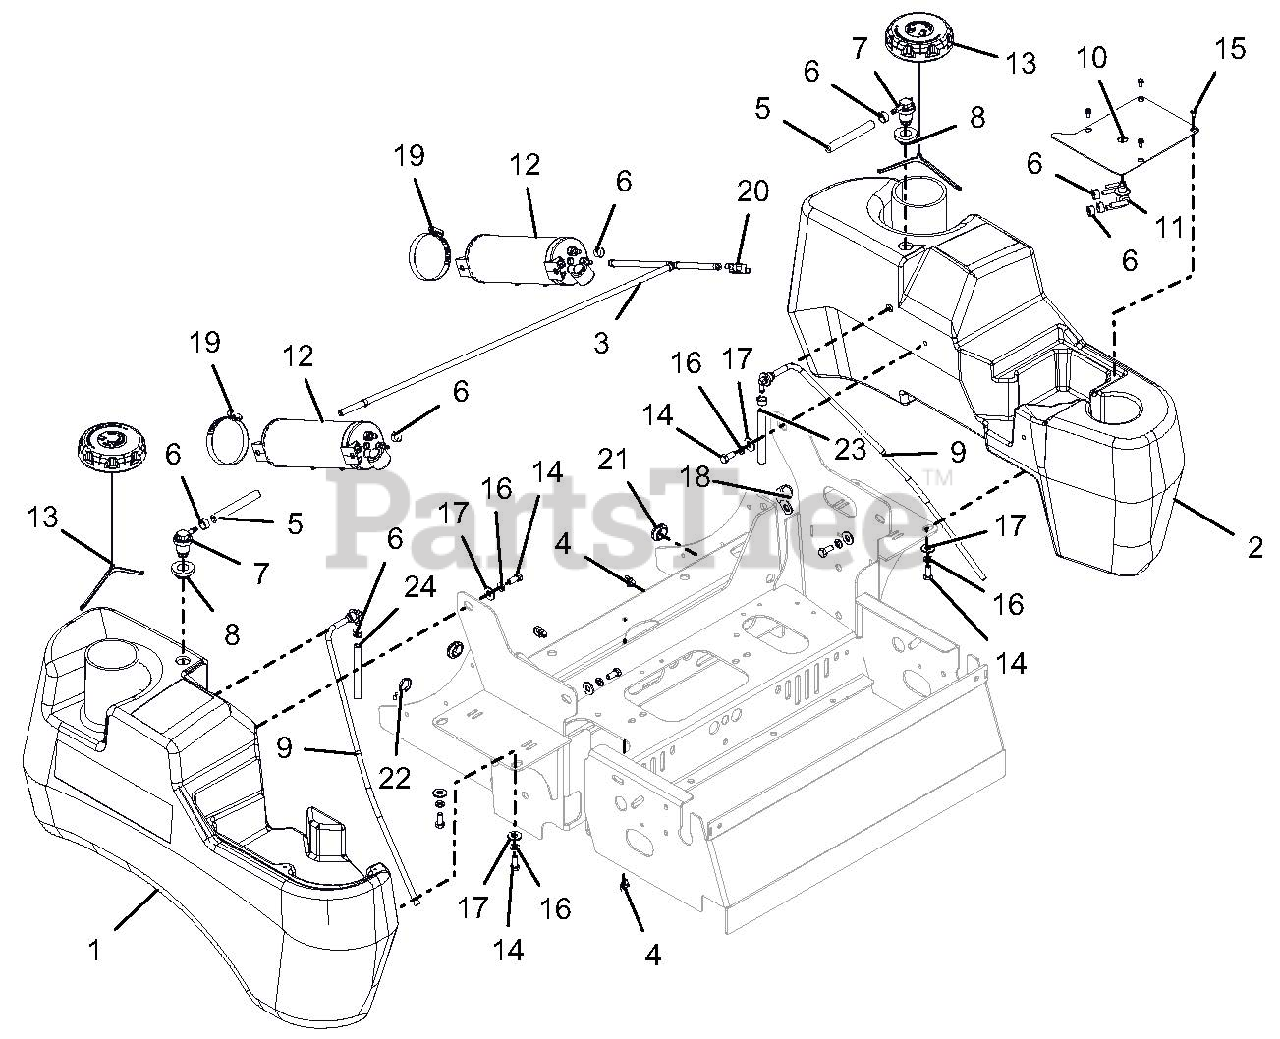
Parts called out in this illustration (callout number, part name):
1	TANK, RH LARGE GRAVELY FUEL
2	TANK, LH LARGE GRAVELY FUEL
3	PT200-400 KAW CARB FUEL LINE ASSEMBLY
4	CLIP, ROUTING
5	.25 LOW-PERM GAS HOSE 19.00" LG - LH TANK TO VALVE
6	CLAMP, FUEL LINE
7	VALVE, COMBINATION
8	GROMMET, REMOTE VENT NITRILE
9	ASM, LARGE TANK FUEL PICKUP
10	PLATE, FUEL VALVE MOUNTING-RED
11	VALVE, FUEL
12	CANISTER, CARBON 9.3 GAL
13	CAP, NON NONVENT AUTOLOCK
14	BLT-HEX .31-18X.75 GR5 YWZC
15	SCR-MCH 10-24X.38 HWHSTAINLESS
16	WSHR-LK .31X.078 REG YWZC
17	WSHR-FL-STL.38X.875X.083 YWZC
18	CLAMP, CUSHIONED STEEL .75
19	CLAMP, HOSE 2.3/3.2
20	CLIP, T, .38-.50
21	GROMMET, RUBBER
22	CABLE TIE W/ TREE
23	.25 LOW-PERM GAS HOSE 14.00" LG - Tank vent to CARB canister
24	.25 LOW-PERM GAS HOSE 54.00" LG - RH TANK TO VALVE
